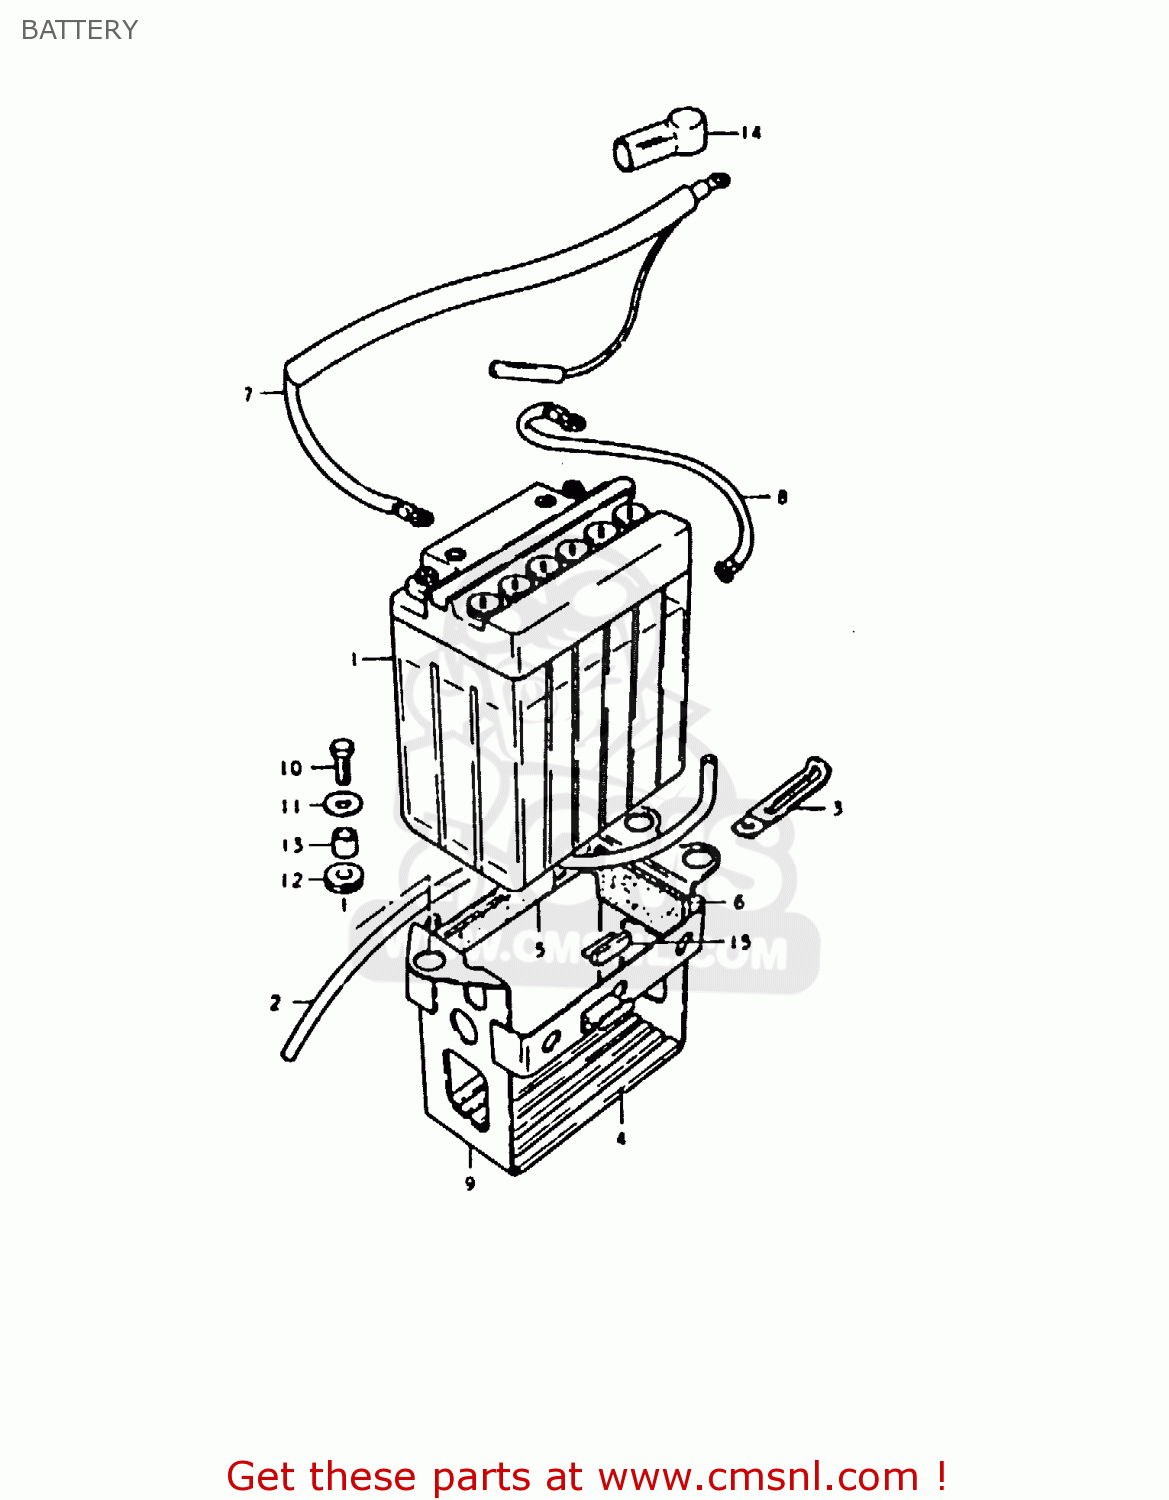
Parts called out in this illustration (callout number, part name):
1	BATTERY ASSEMBLY
2	HOSE,BATTERY EXHAUST
3	CLAMP L:35
4	PROTECTOR,BATTERY
5	PROTECTOR(20X90)X4
6	PROTECTOR,BATTERY
7	WIRE,BATTERY PLUS
8	LEAD WIRE,BATTERY(-)
9	HOLDER,BATTERY
10	BOLT, UPPER
11	WASHER
12	CUSHION
13	SPACER(6.1X9X7.5)
14	CAP,TERMINAL
15	CUSHION,FRAME COVER
